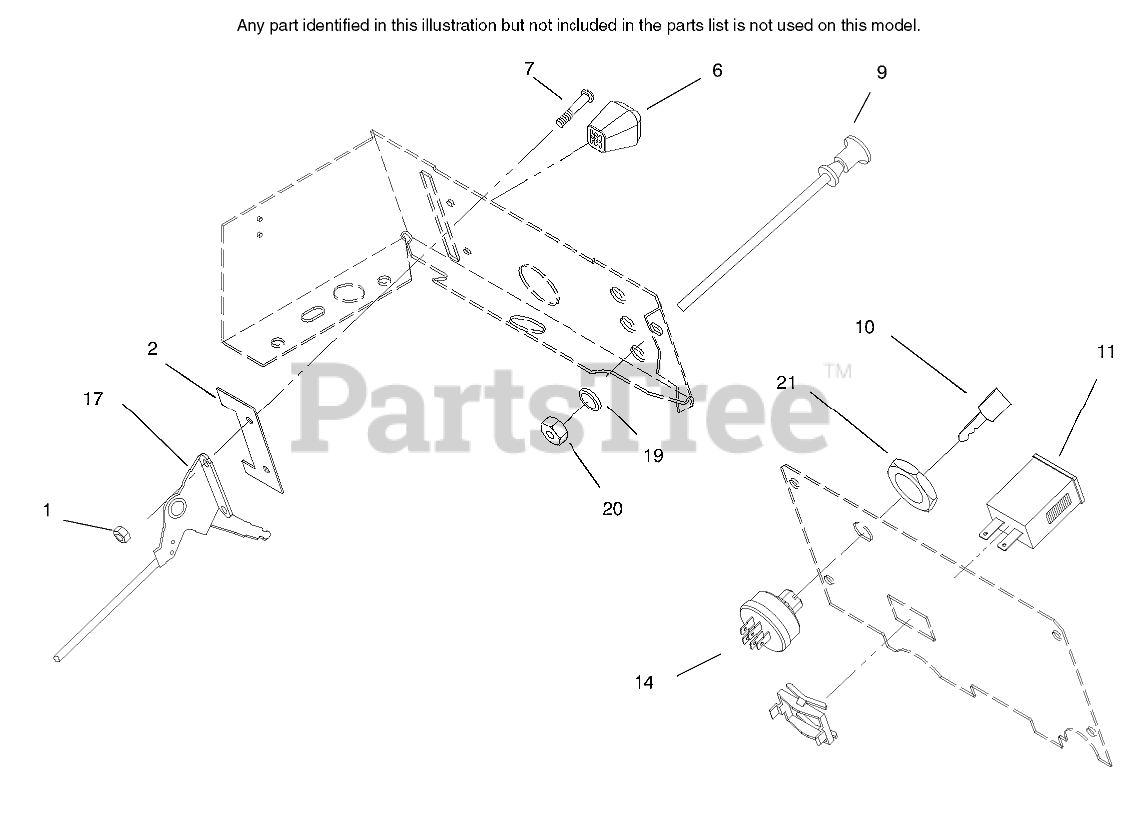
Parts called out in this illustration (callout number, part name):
1	Nut
2	STOP-THROTTLE
7	SCRW-PHC
9	CHOKE CONTROL ASM
10	KEY-IGNITION
11	HOURMETER
14	SWITCH-IGNITION
17	THROTTLE CONTROL ASM
19	WASHER-FLAT
20	NUT-HEX PALNUT
